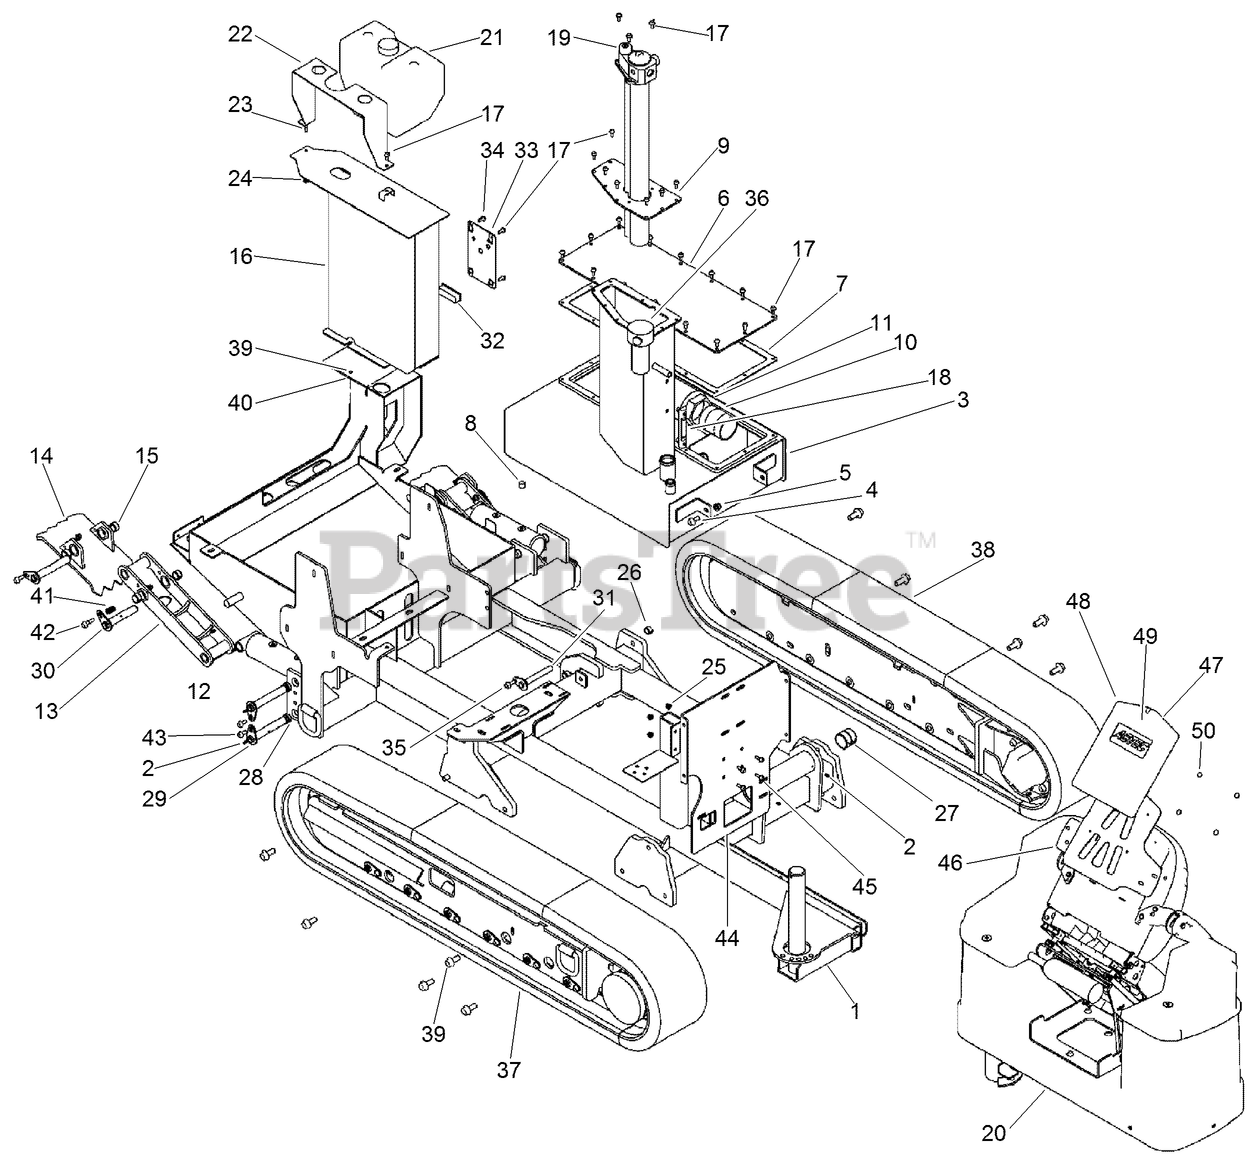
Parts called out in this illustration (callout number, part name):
1	FRAME - Main
2	FITTING-Lube 1/4-28 Tpr SAE-LT .54 Long
3	TANK - Hydraulic
4	SCREW, METRIC FLANGE w/BODY-M12 x 30
5	NUT-HHF, LOCK
6	PLATE - Hydraulic Tank Cover
7	GASKET-COVER LID, HYDRAULIC TANK
8	PLUG-PIPE, HEX SOCKET
9	PLATE - Hydraulic Tank Lid
10	NIPPLE-PIPE
11	STRAINER-SUCTION, 100 MESH
12	HYD CYLINDER ASM
13	WELDMENT - Stabilizer Leg
14	WELDMENT - Stabilizer Foot
15	BUSHING-SPRING
16	WELDMENT - Rear Controls Box
17	SCREW, METRIC FLANGE w/BODY - M8 x 20
18	GAUGE-SIGHT
19	FILTER ASM (HYDRAULIC TANK)
20	ASSEMBLY - Operators Console
21	BOTTLE - Mud Pump System Anti-Freeze
22	BRACKET - Anti-Freeze Bottle
23	SCREW, METRIC FLANGE w/BODY - M8 x 45
24	NUT, METRIC HEX FLANGE - M8, Zinc
25	NUT-TORQUE, PREVAILING
26	BUSHING-SPRING
27	BUSHING-SPRING
28	BUSHING-SPRING
29	PIN-FLAG
30	PIN-FLAG
31	PIN-FLAGGED
32	LATCH-TRIGGER, RAISED (W/LOCK)
34	PLATE - Rear Controls Panel
35	SCREW-HH
36	FILTER-HYD, 350PSI (6 MICRON)
37	ASSEMBLY - Track RH
38	ASSEMBLY - Track LH
39	SCREW-HHF
40	NUT-FLANGE, NYLOCK
41	WASHER - 0.406 x 0.750 x 0.119 in CST ZND
42	SCREW-HHF
43	SCREW-FLANGE
44	PLATE - Fuse Box Mount
45	SCREW-HH
46	PLATE - Operators Manual Case Mounting
47	HOLDER-MANUAL, OPERATOR
48	LANYARD
49	POST-MANUAL
